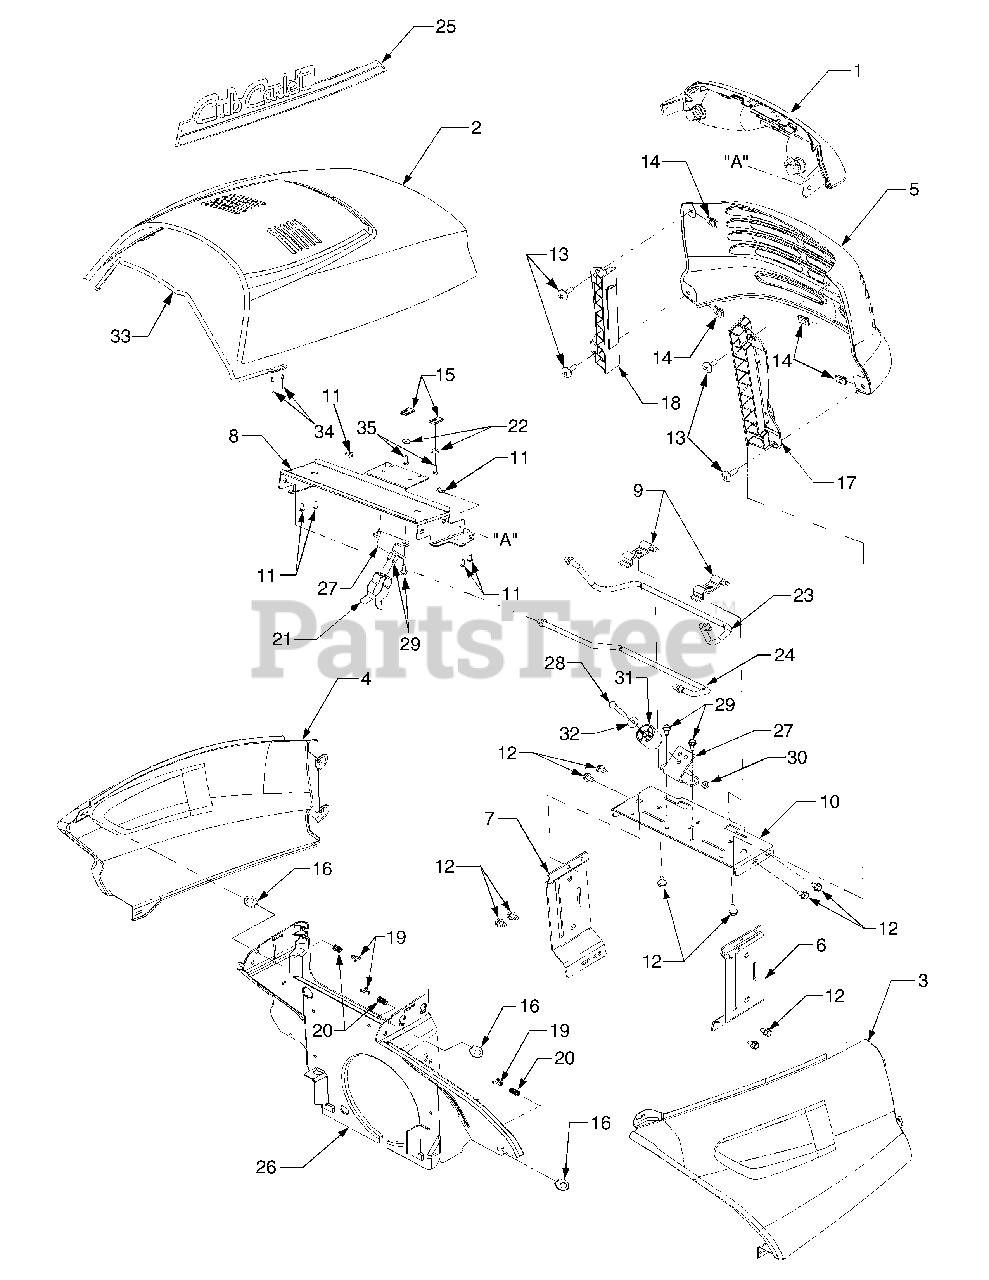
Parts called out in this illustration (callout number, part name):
1	Headlight Assembly
1	Bulb, Headlight
1	Socket Assembly, Headlight
2	Graphic, Hot Surface
3	Side Panel, RH
3	Graphic, GT 3200
3	Graphic, Lift Hood
4	Side Panel, LH
4	Graphic, GT 3200
4	Graphic, Lift Hood
5	Grille, Series 3000
5	Graphic, Warning
6	Support, Grille - RH
7	Support, Grille - LH
8	Bracket, Upper Hood
8	Graphic, Hot Surface
9	Bracket, Rod Retainer
10	Support, Hood
11	Screw, Truss Hd, Tapp, #10-16 x .5
12	Screw, Hex Wash. Hd. Tapp 5/16-18 x .5
13	Screw, Phil. Pan Hd. 1/4-20 x .75
14	Nut, U Type Speed, 1/4-20
15	Nut, U-type Speed, #10
16	Latch, 1/4 Turn
17	Mount, Side Panel/Grille RH
18	Mount, Side Panel/Grille LH
19	Clip, Spring
20	Spring, Compression
21	Spring, Hood Latch
22	Washer, Flat, .194 x .62 x .063
23	Rod, Upper Hood
24	Rod, Lower Hood
25	Graphic, Hood - RH
25	Graphic, Hood - LH
26	Baffle, Lower Air
27	Bracket, Hood Latch Support
28	Screw, Hex Cap, 1/4-20 x 1.75 GR5
29	Screw, Hex Wash Hd Tapp, 1/4-14 x .5
30	Nut, Hex Top Lock, 1/4-20
31	Roller, Hood Latch
32	Washer, Flat, .283 x .75 x .030
33	Rod, Hood Support
34	Rivet, Pop, .125 OD
35	Screw, Hex Tapp, #10-16 x .625
